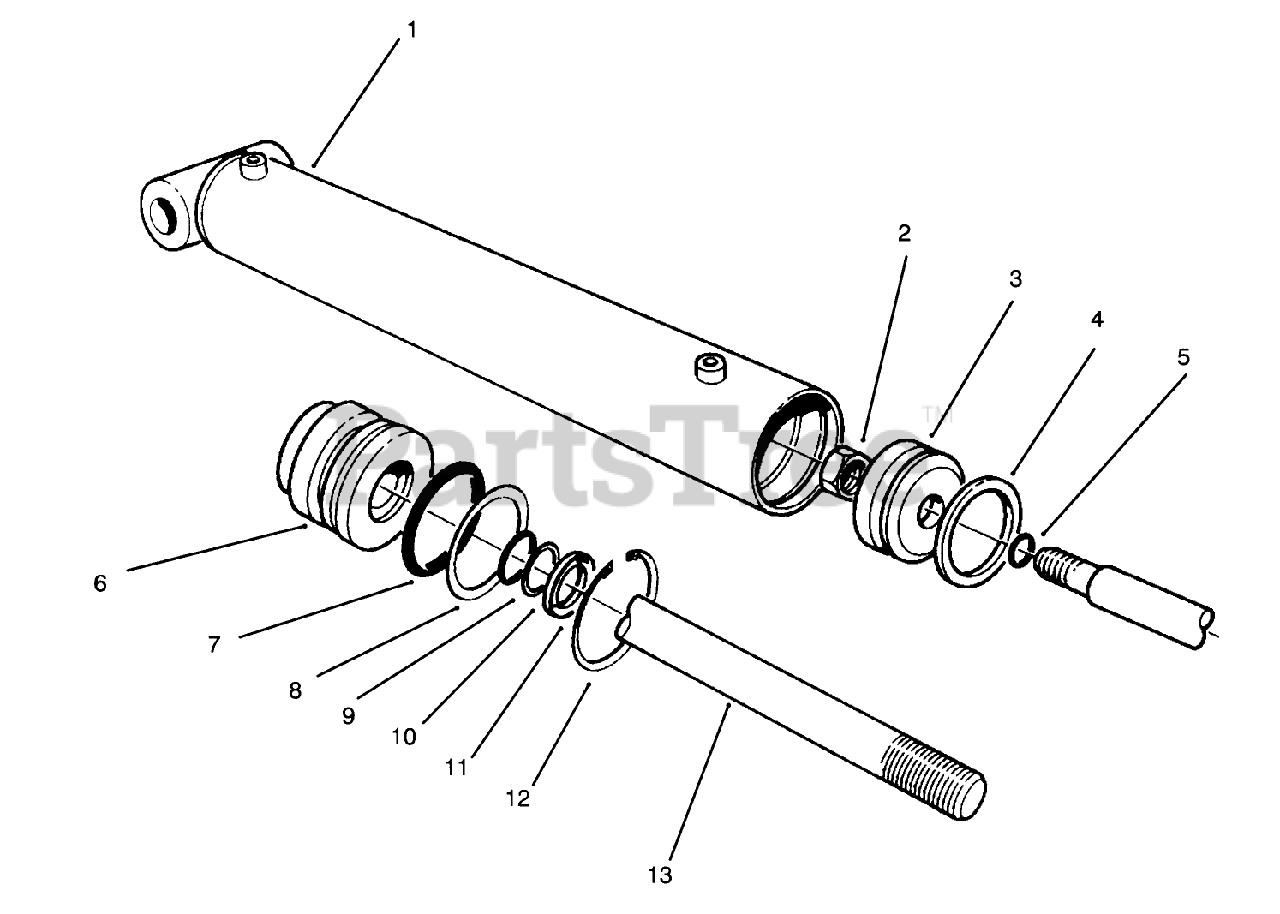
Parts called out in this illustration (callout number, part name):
1	Barrel
2	LOCKNUT
3	PISTON
5	"O" Ring
7	"O" Ring
9	"O" Ring
12	RING-RETAINING
13	SHAFT
